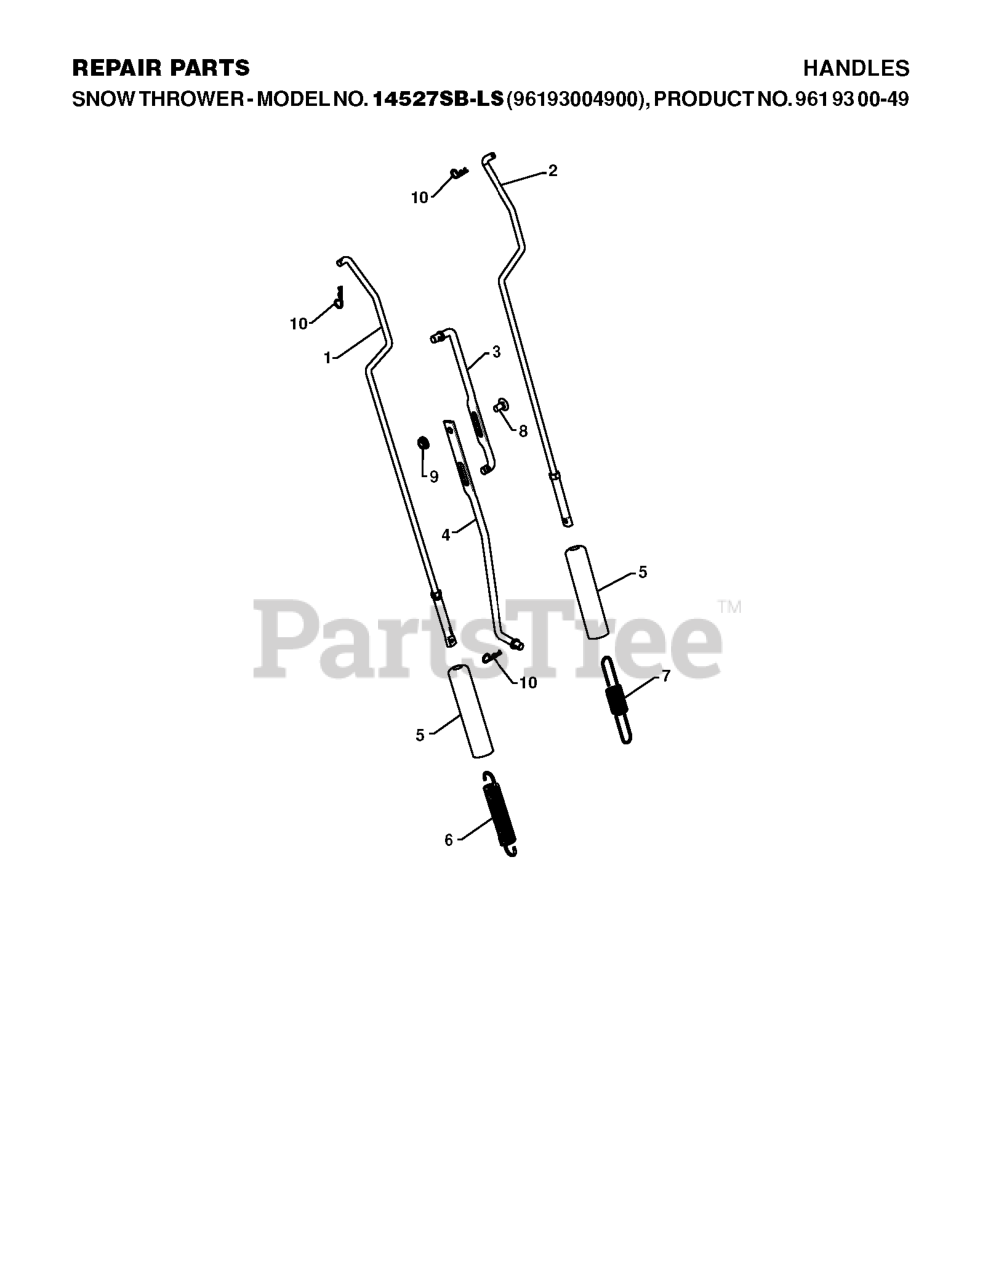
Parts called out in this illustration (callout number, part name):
1	ROD.ASM.IMPELLER
2	ROD.ASM.TRACTION
3	ROD, UPPER SPEED CONTROL
4	ROD, LOWER SPEED CONTROL.SNOW
5	SLEEVE, SPRING
6	SPRING, AUGER CONTROL
7	SPRING, TRACTION DRIVE
8	BOLT
9	NUT.FLANGE.5/16
10	SPRING RETAINER
